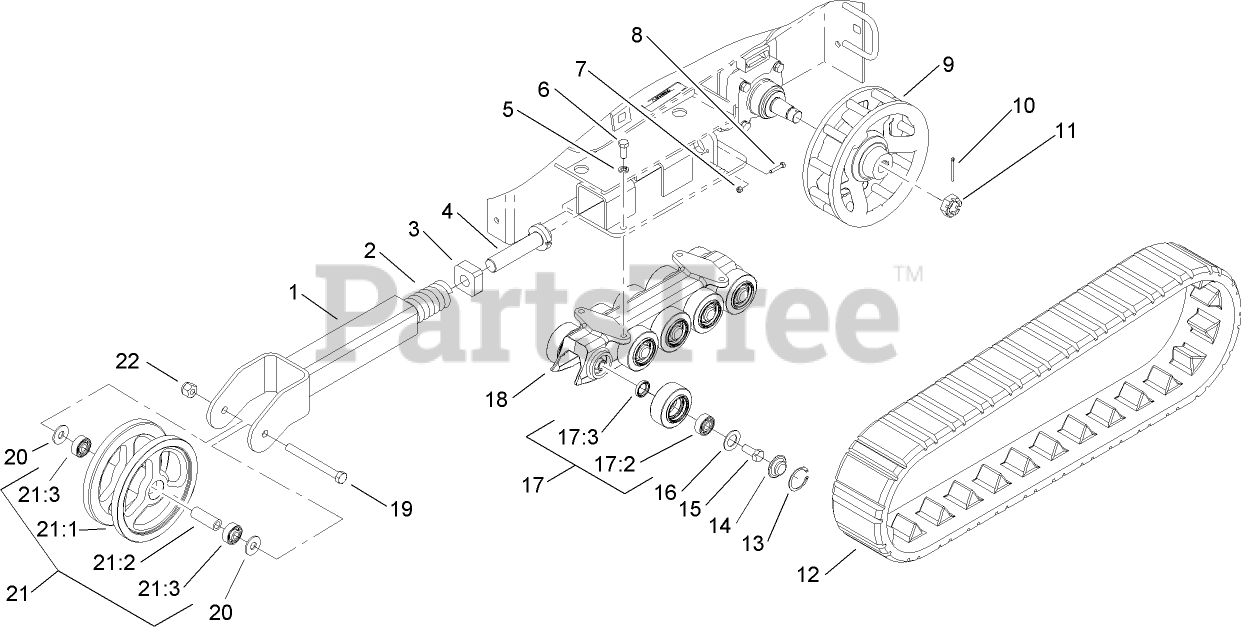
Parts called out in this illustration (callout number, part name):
1	TENSIONER ARM ASM
2	SPRING-COMPRESSION
3	BLOCK-TENSIONER
4	BOLT-TENSIONER
5	WASHER-LOCK
6	SCREW-HH
7	NUT-LOCK, NI
8	SCREW-HH
9	WHEEL-DRIVE, TX 420
10	PIN-COTTER
11	NUT-HEX SLOTTED
12	TRACK
13	RING-SNAP, INTERNAL
14	CAP-WHEEL, BEARING
15	SCREW-HH
16	Gasket-Bogie
17	Road Wheel ASM
17:2	BEARING
17:3	SEAL-OIL
18	GUIDE-TRACK
19	SCREW-HH
20	WASHER-FLAT
21	TENSIONER WHEEL ASM
21:1	WHEEL-TENSIONER
21:2	SPACER-WHEEL, TENSIONER
21:3	BEARING
22	NUT-HEX
